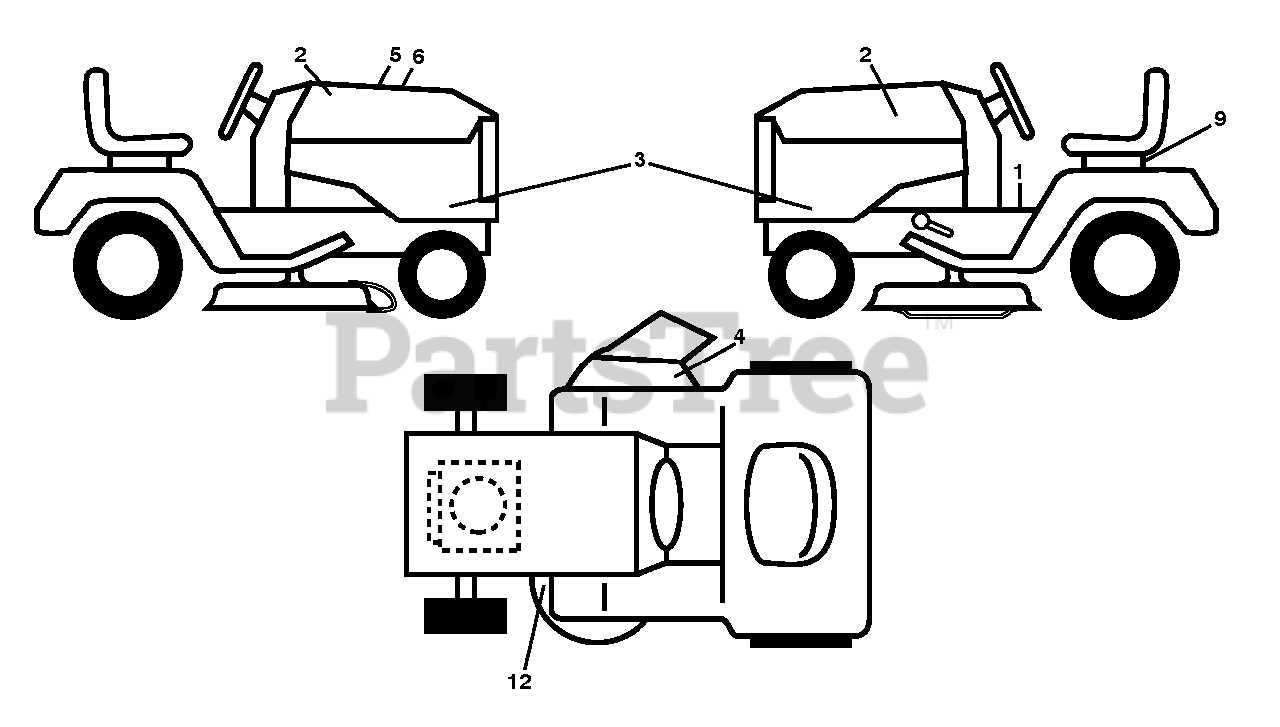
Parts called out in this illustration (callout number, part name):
1	DECAL.WARNING.2007.ENG/FR
2	DECAL.BADGE.170MM.TEXTLOGO.
3	DECAL.SDPNL.HUSGT2.SET.YTH2146
4	DECAL.MOWER.WARN.KEEP.HAND.AWY
5	DECAL.WARNING.CUST.RESP.E85.
6	DECAL.PRL.BSM33.TLW.46.46K
9	DECAL BTRY SYMBOLS
12	DECAL.V-BELT.SCH.42/46"MEC/ELE
